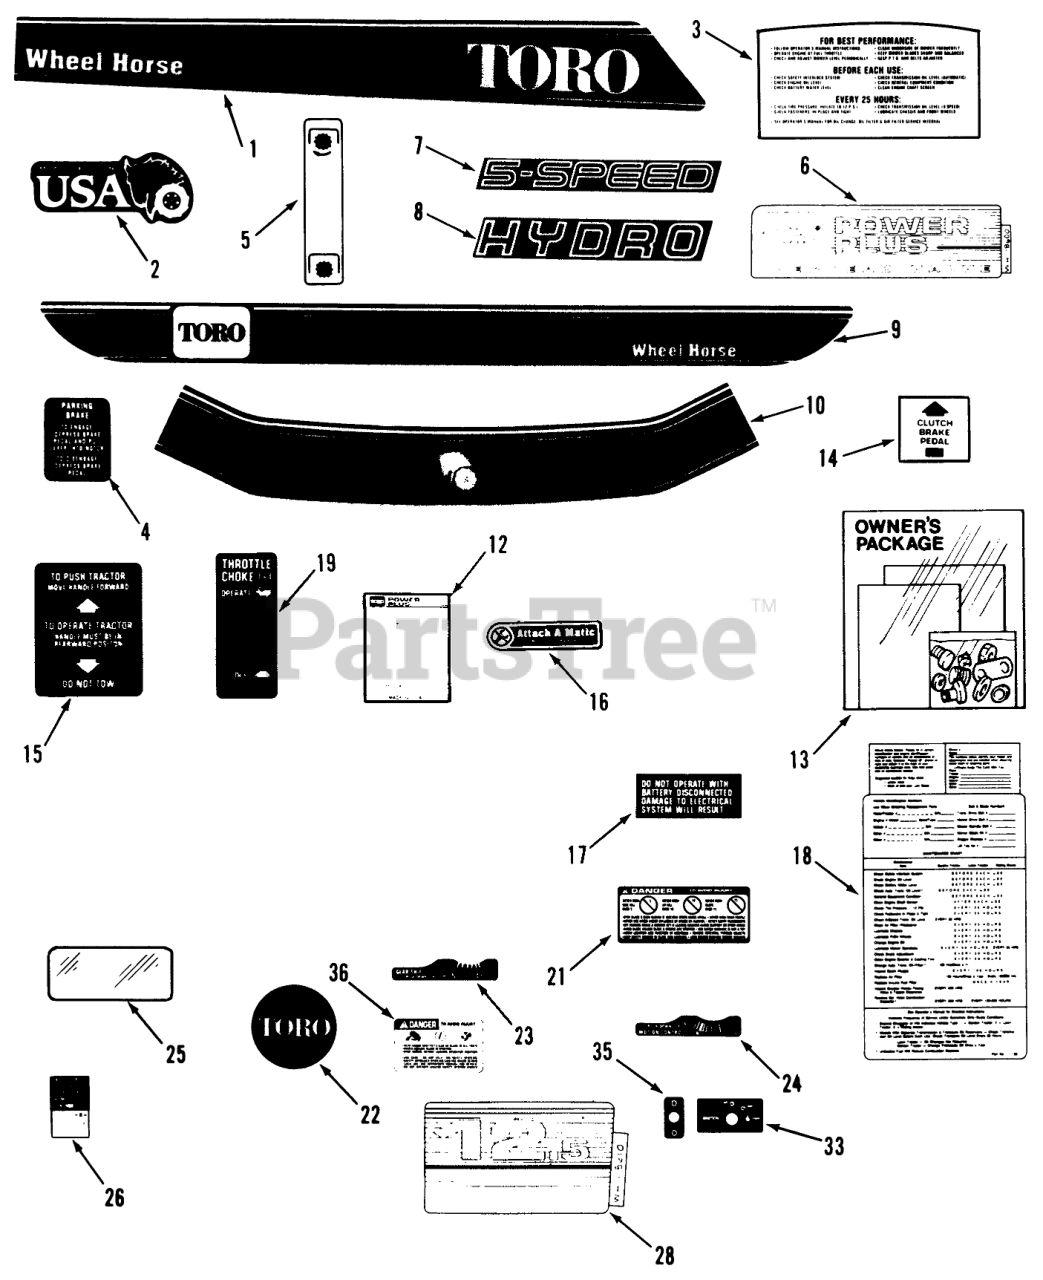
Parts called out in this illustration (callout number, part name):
1	DECAL-HOOD 210-5 R H
2	Decal-Made In USA
3	Decal-Hood Rear
4	DECAL PARKING BRAKE
5	DECAL-PTO
6	DECAL-PWR PLUS
7	DECAL-MODEL 5-SPEED
8	DECAL-MODEL HYDRO
9	DECAL-FENDER
10	DECAL-FRONT HOOD
13	Loose Parts Package (210-5)
14	DECAL CLUTCH & BRAKE
15	DECAL-PUSH
16	Decal-Attach-A-Matic
17	DECAL ELECT SYSTEM
18	MAINTENANCE-DECAL
19	DECAL-THROTTLE
21	DECAL-DANGER
22	DECAL-TORO ENGINE
23	DECAL-SHIFT 5-SPEED
24	DECAL-MOTION CONTROL
25	DECAL-OVERLAY
26	DECAL-PTO BELT ADJ
28	DECAL-PWR PLUS 12.5
33	DECAL-IGNITION
35	DECAL-LIGHTS
36	Decal-Danger
